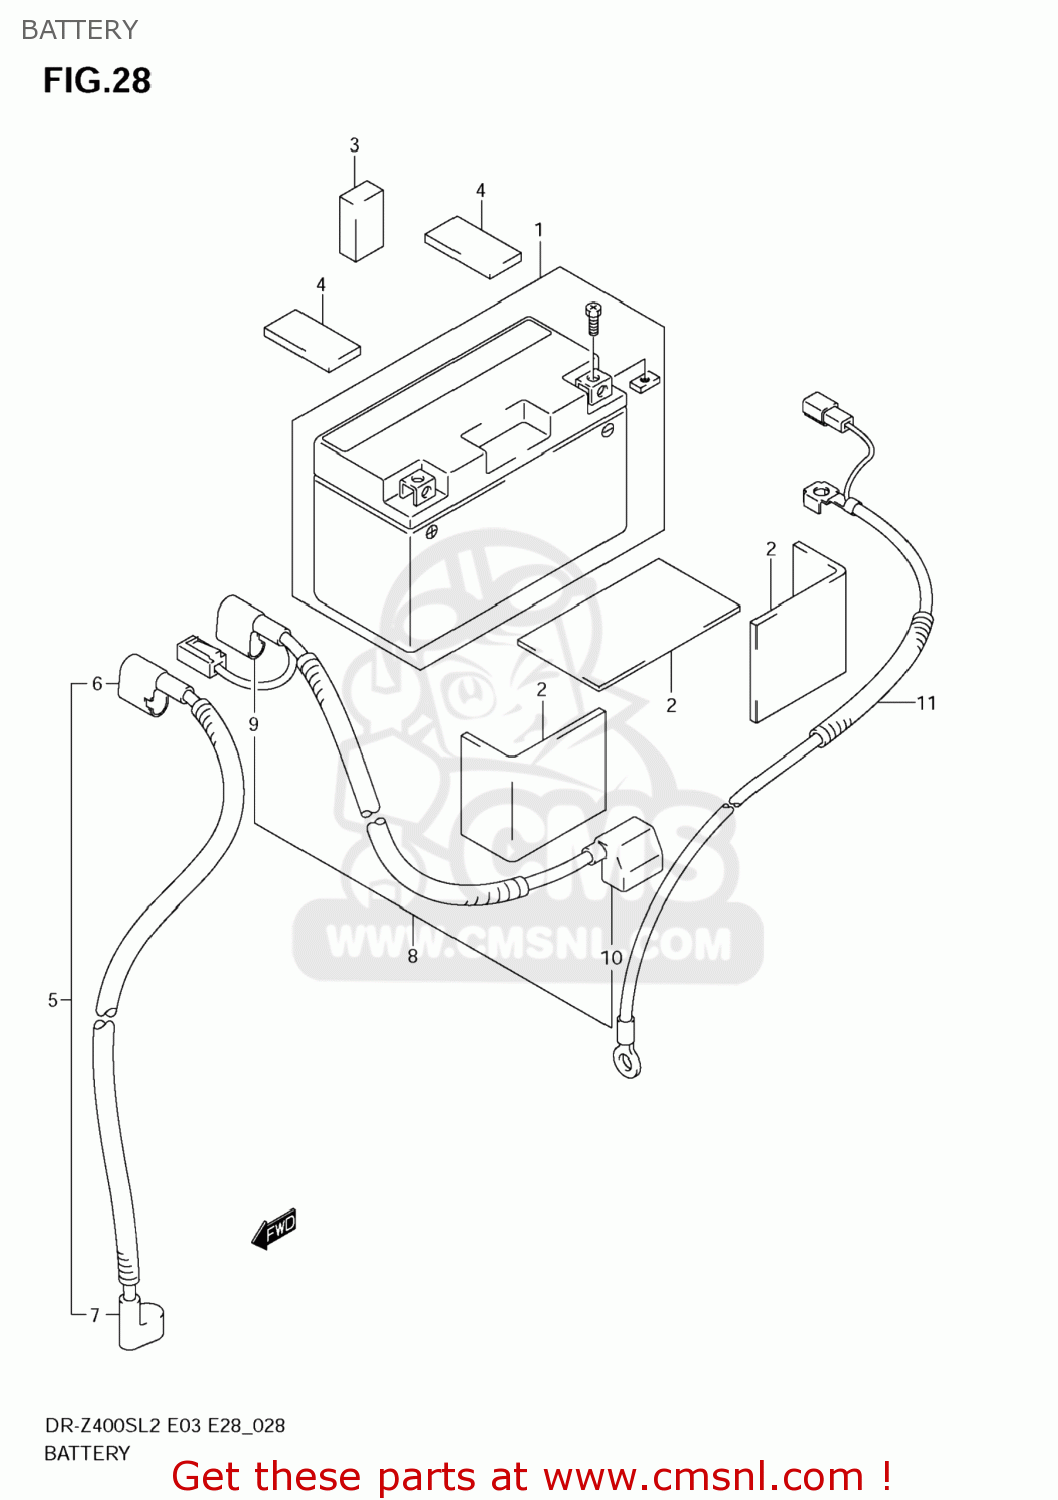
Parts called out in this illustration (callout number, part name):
1	BATTERY ASSY(YT7B-BS,12V6AH)
2	PROTECTOR(170X95X3.0)
3	PROTECTOR,BATTERY(70X100X6)
4	CUSHION(50X42X2.0)
5	WIRE,STARTER MOTOR LEAD
6	CAP,STARTER RELAY
7	CAP,STARTER MOTOR
8	WIRE,BATTERY PLUS LEAD
9	CAP,STARTER RELAY
10	CAP,BATTERY PLUS
11	WIRE,BATTERY MINUS LEAD
